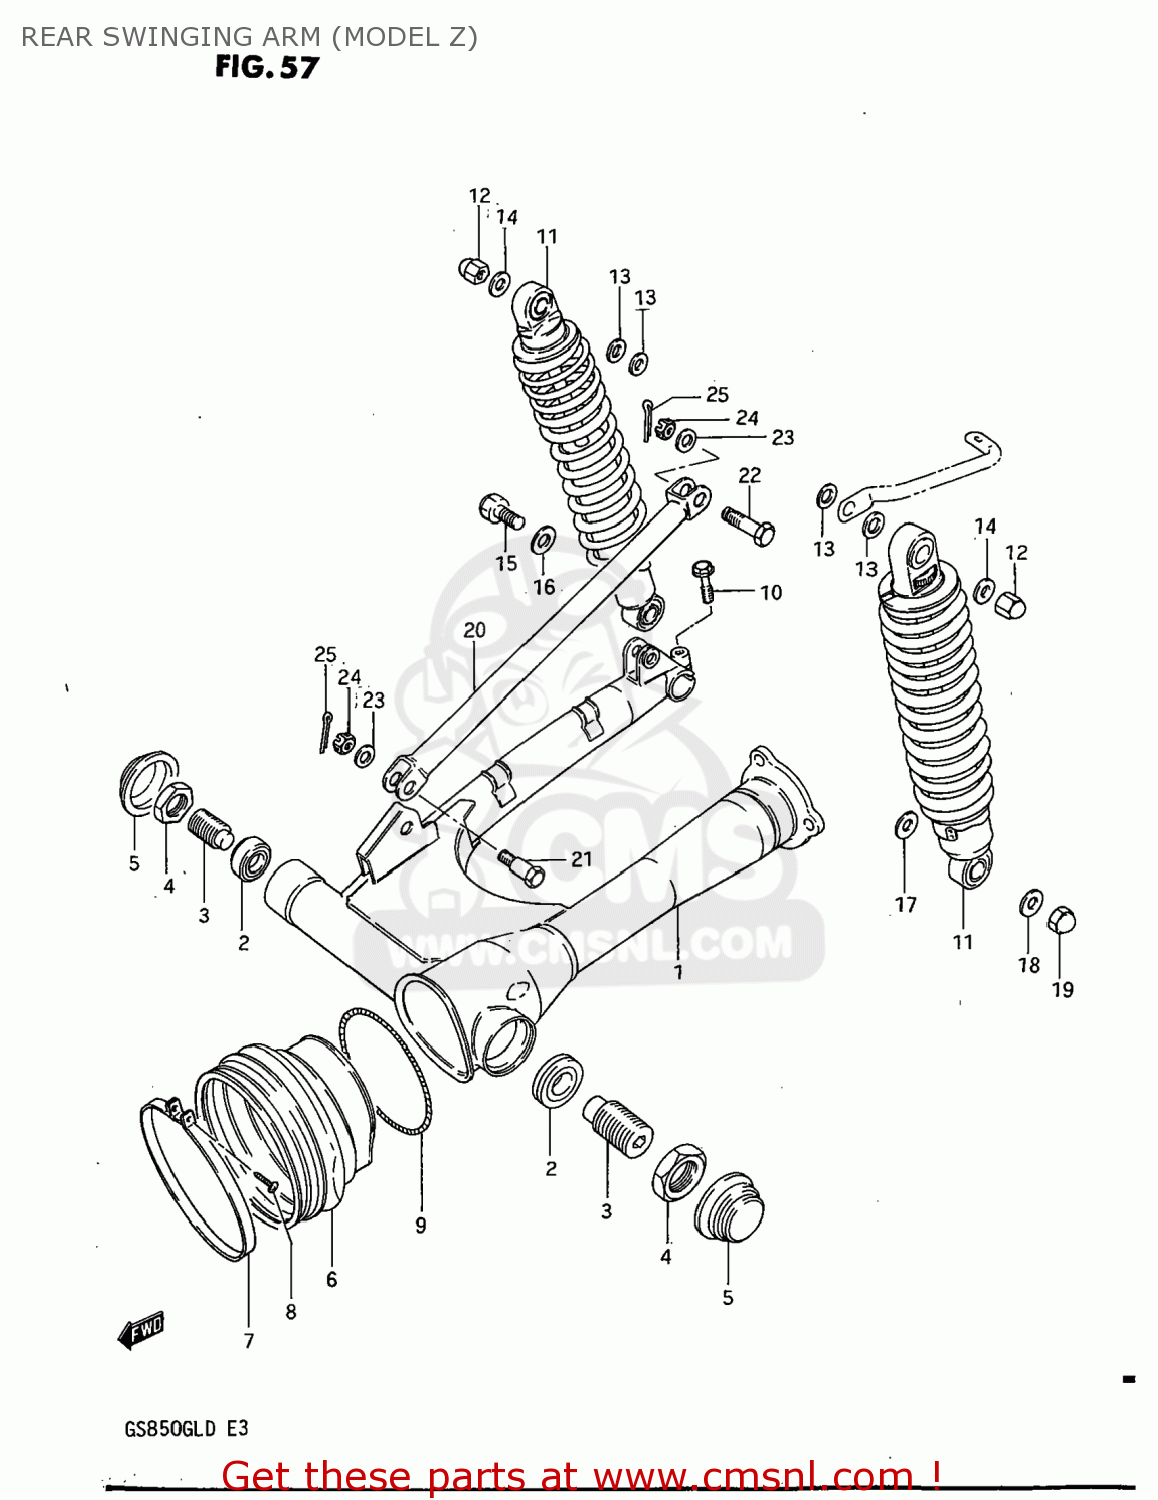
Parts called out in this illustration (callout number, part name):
1	SWING ARM SET,REAR (B
2	BEARING(17X40X13.25)
3	BOLT,REAR SWING ARM PIVOT
4	NUT
5	CAP,REAR SWING ARM PIVOT
6	BOOT,PROPELLER SHAFT
7	CLAMP
8	SCREW 4X25
9	SPRING,PROPELLER SHAFT
10	BOLT
11	ABSORBER ASSEMBLY,REAR SHOCK
12	NUT
13	WASHER
14	WASHER
15	BOLT 12X33
16	WASHER (12.5X24X1.6)
17	WASHER
18	WASHER
19	NUT, LOWER LH
20	TORQUE LINK,REAR
21	BOLT
22	BOLT(10X39)
23	WASHER
24	NUT
25	PIN 20X20
